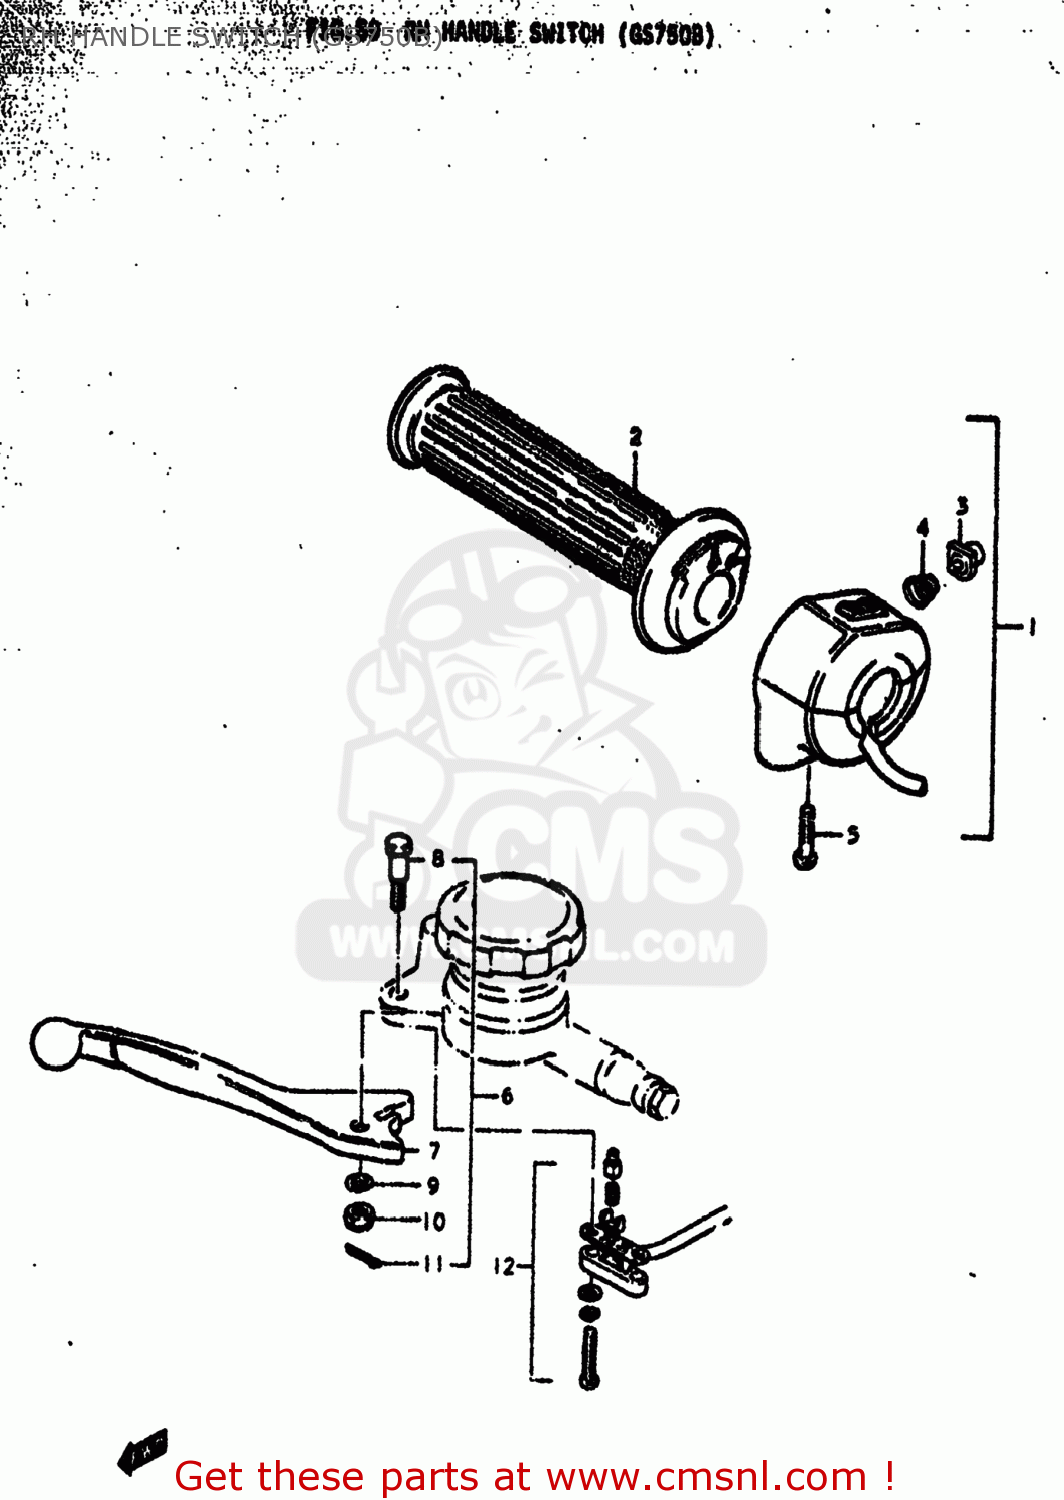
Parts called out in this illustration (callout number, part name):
1	GRIP ASSEMBLY,THROTTLE
2	GRIP,THROTTLE
3	BUTTON
4	SPRING
5	SCREW
6	LEVER ASSEMBLY,BRAKE
7	LEVER,BRAKE
8	BOLT,LEVER
9	LOCK WASHER
10	NUT,LEVER FITTNG
11	COTTER PIN
12	SWITCH ASSY,STOP
